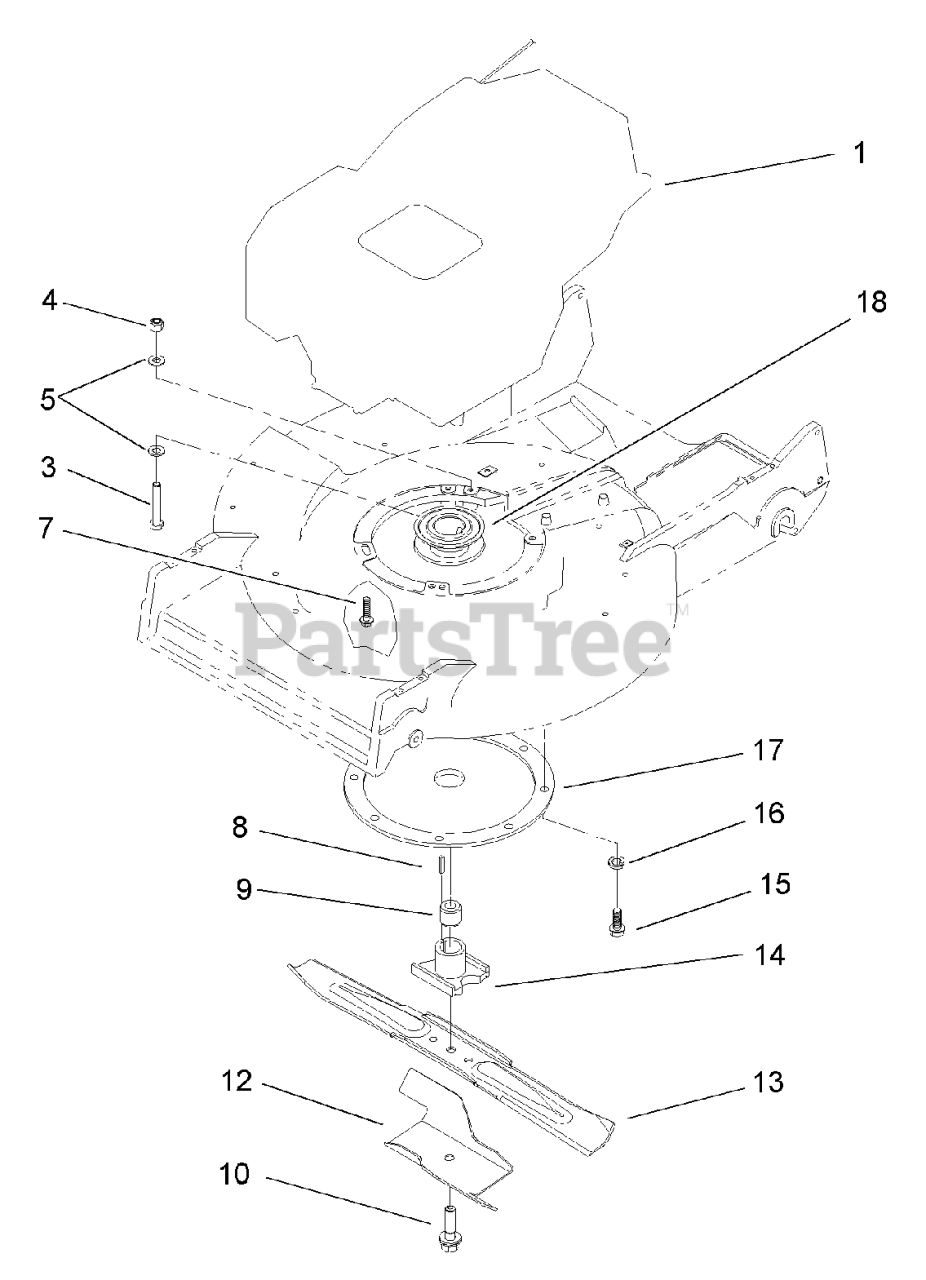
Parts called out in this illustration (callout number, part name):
3	SCREW-HH
4	NUT-LOCK, NI
5	WASHER-PLAIN
7	SCREW-SHOULDER
8	KEY-SQUARE
9	SPACER-RETAINER, BLADE
12	STIFFENER-BLADE
14	RETAINER-BLADE
15	Screw-HWH 5/16-18 X 3/4 Tf
16	WASHER-LOCK, INTERNAL
18	PULLEY-DRIVER
